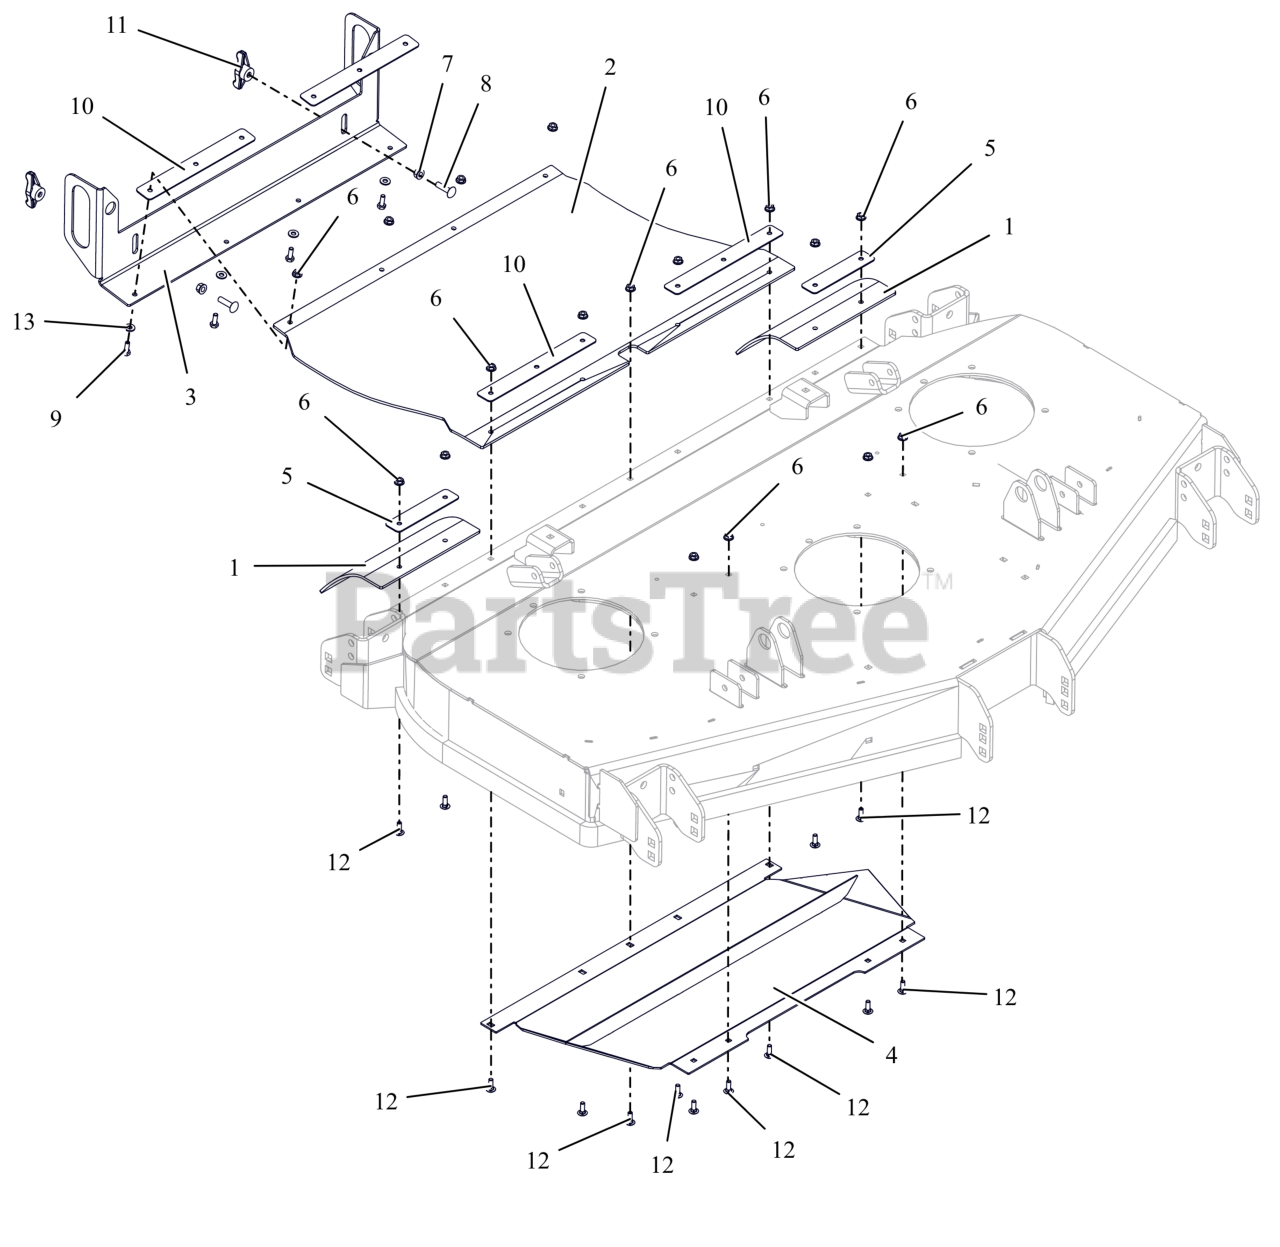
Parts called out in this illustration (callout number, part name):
1	CHUTE- 52" REAR DISCHARGE TIRE
2	CHUTE- 52" REAER DISCHARGE
3	HANDLE, CHUTE MOUNTING (RED)
4	WLDMT- 52" DEFLECTOR BAFFLE
5	PLATE- 52" TIRE CHUTE MTG
6	NUT-LK-CTR-FLG .25-20 ZC120
7	NUT,LK-CTR-FLG .31-18 GF ZCC
8	BTL,RHSSN .313-18 X 1.25 G5 ZCC
9	BLT, HEX .25-20X.75 G5 ZCC
10	PLATE, CHUTE MTG (BLACK)
11	KNOB,WING .31-18 UNC NYL/TALC
12	BLT, RHSN .25-20X.750 G5 ZCC
13	WSHR,FLT .281X.625X.065 ZCC
